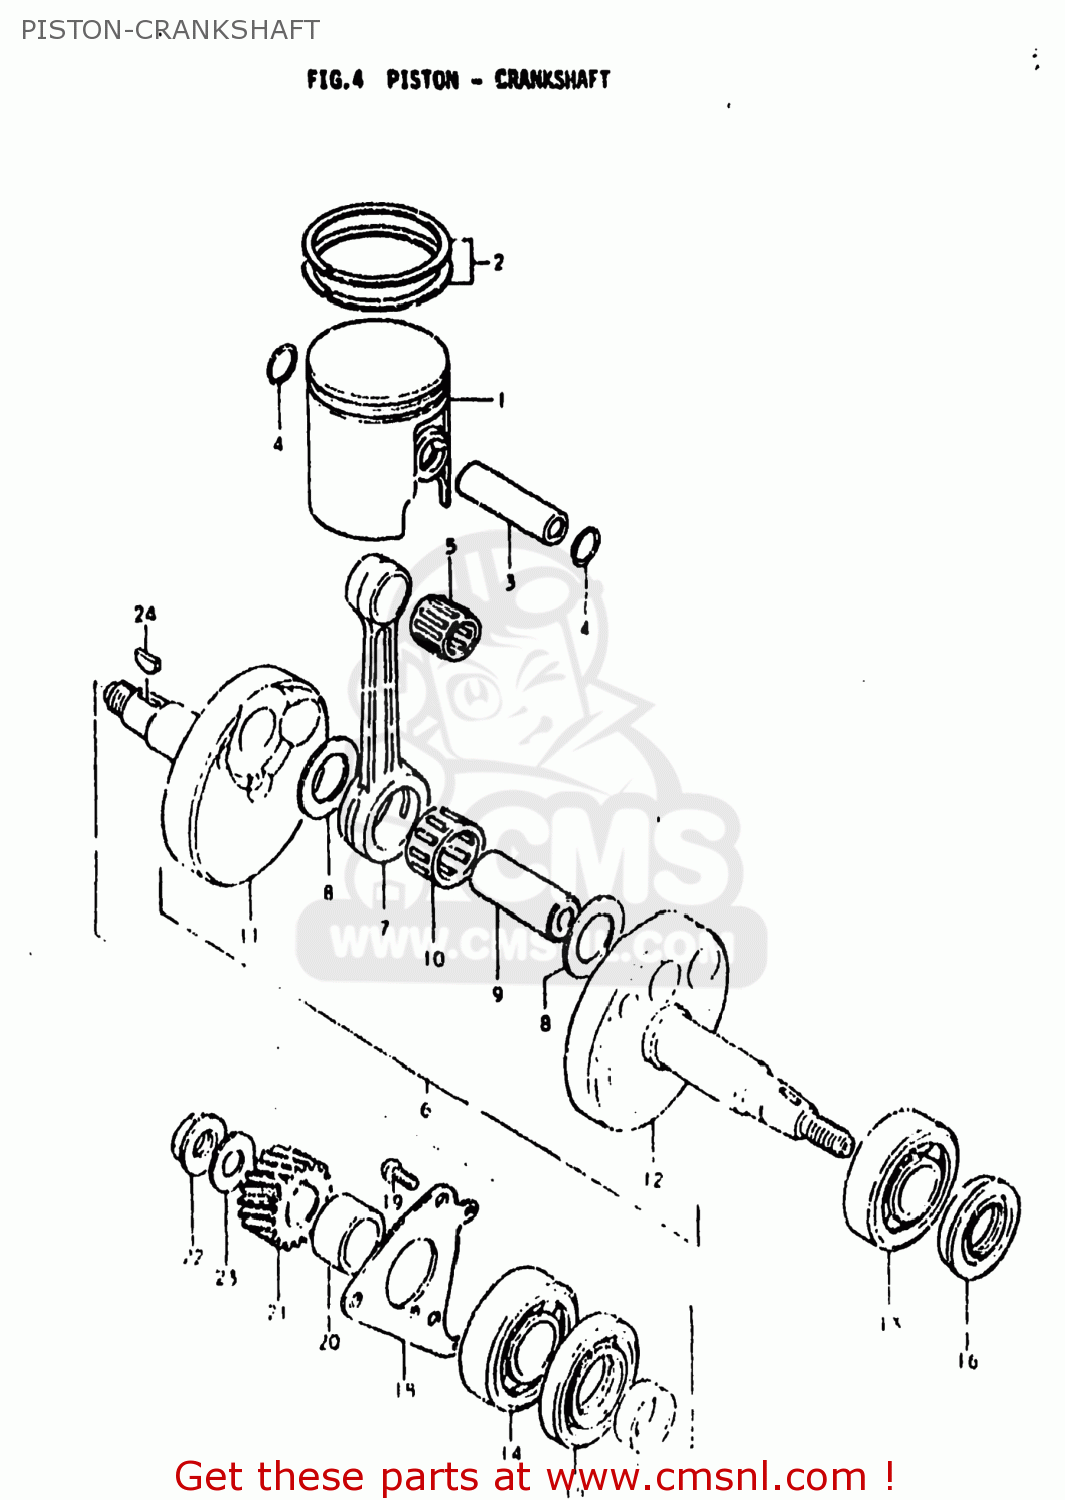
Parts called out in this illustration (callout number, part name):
1	PISTON
2	RING SET,PISTON
3	PIN,PISTON
4	RING,SNAP
5	BEARING
6	CRANKSHAFT ASSEMBLY
7	CONNECTING ROD
8	WASHER
9	PIN,CRANK
10	BEARING
11	CRANKSHAFT,RIGHT
12	CRANKSHAFT,LEFT
13	BEARING
14	BEARING
15	OIL SEAL
16	OIL SEAL
17	SPACER(20X26X9)
18	RETAINER,CRANKSHAFT BEARING,R
19	SCREW 6X12
20	SPACER(20X26X14)
21	GEAR,PRIMARY DRIVE NO.19
22	NUT
23	WASHER
24	KEY
